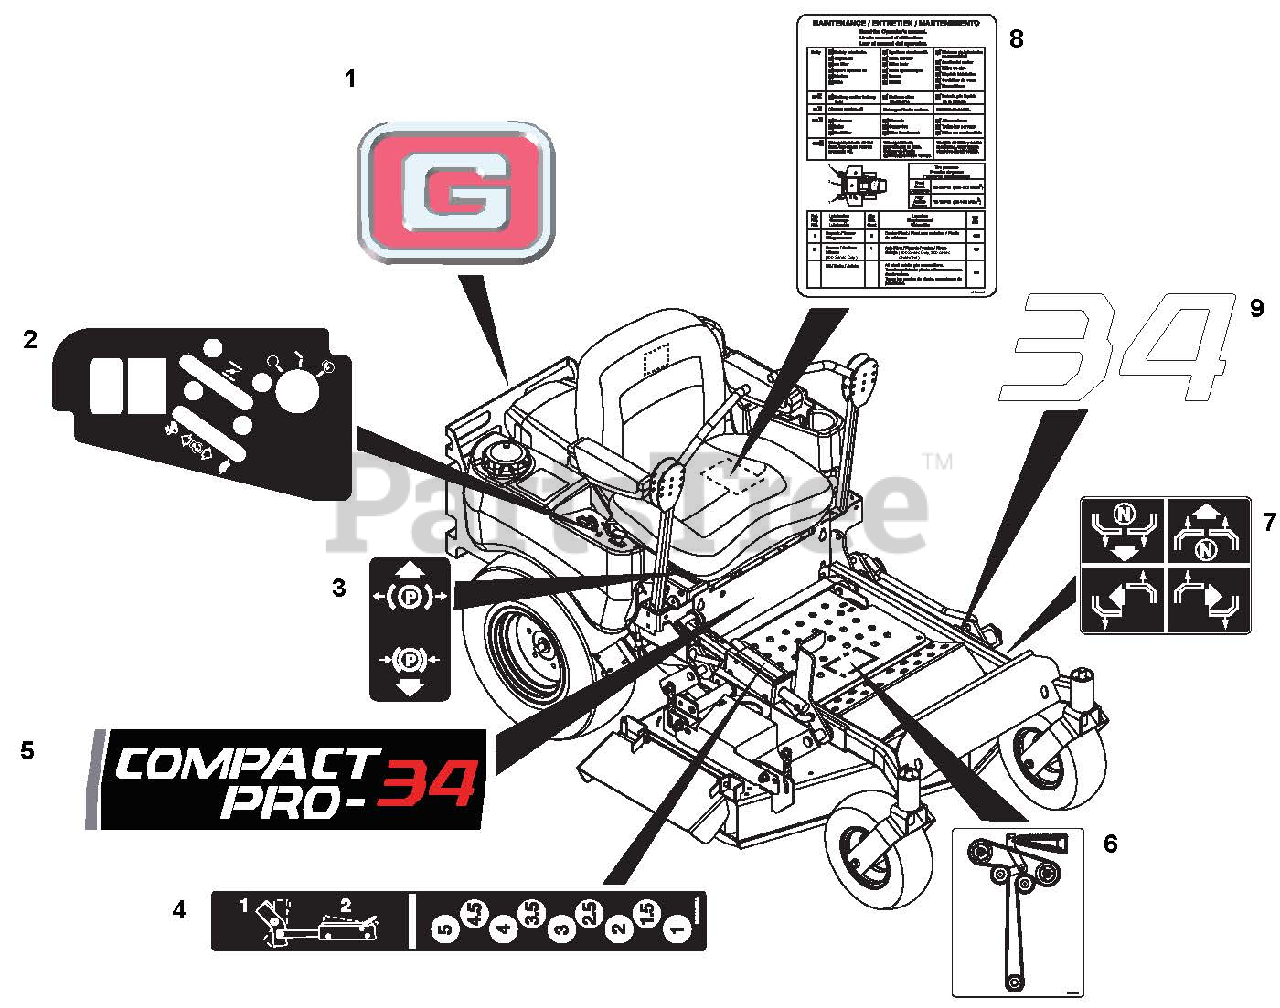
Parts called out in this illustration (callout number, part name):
1	Decal, Gravely Brand
2	Decal, Control Panel
3	Decal, Parking Brake Lever
4	Decal, Height of Cut
5	Decal, Compact Pro 34 Brand
6	Decal, Belt Diagram
7	Decal, Instructional Steering
8	Decal, Maintenance Instructions
9	Decal, 34"
